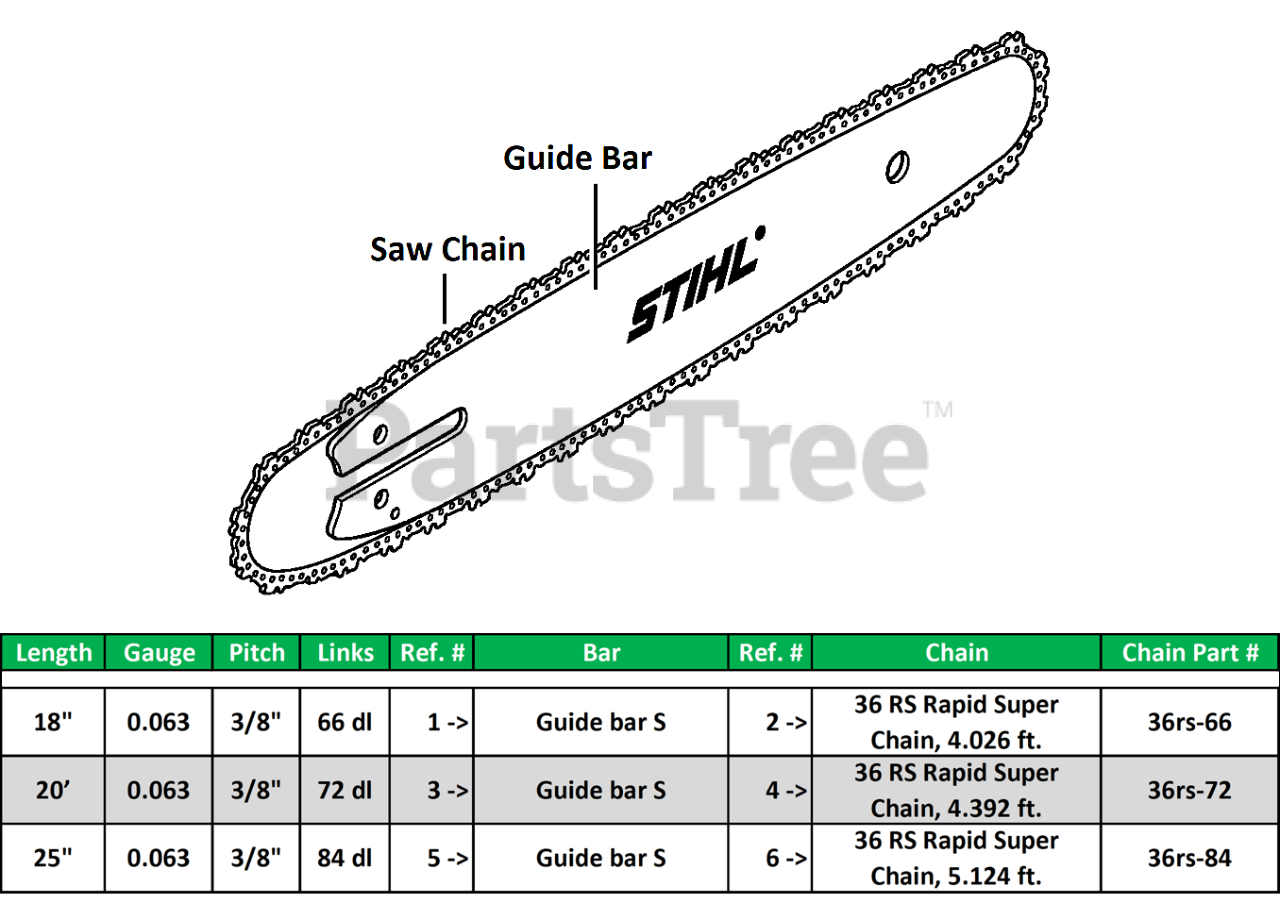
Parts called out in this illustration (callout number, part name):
1	Guide bar S 45cm/18" 1,6mm/0.063" 3/8"
2	36 RS Rapid Super Chain, 4.026 ft.
3	Guide bar S 50cm/20" 1,6mm/0.063" 3/8"
4	36 RS Rapid Super Chain, 4.392 ft.
5	Guide bar S 63cm/25" 1,6mm/0.063" 3/8"
6	36 RS Rapid Super Chain, 5.124 ft.
